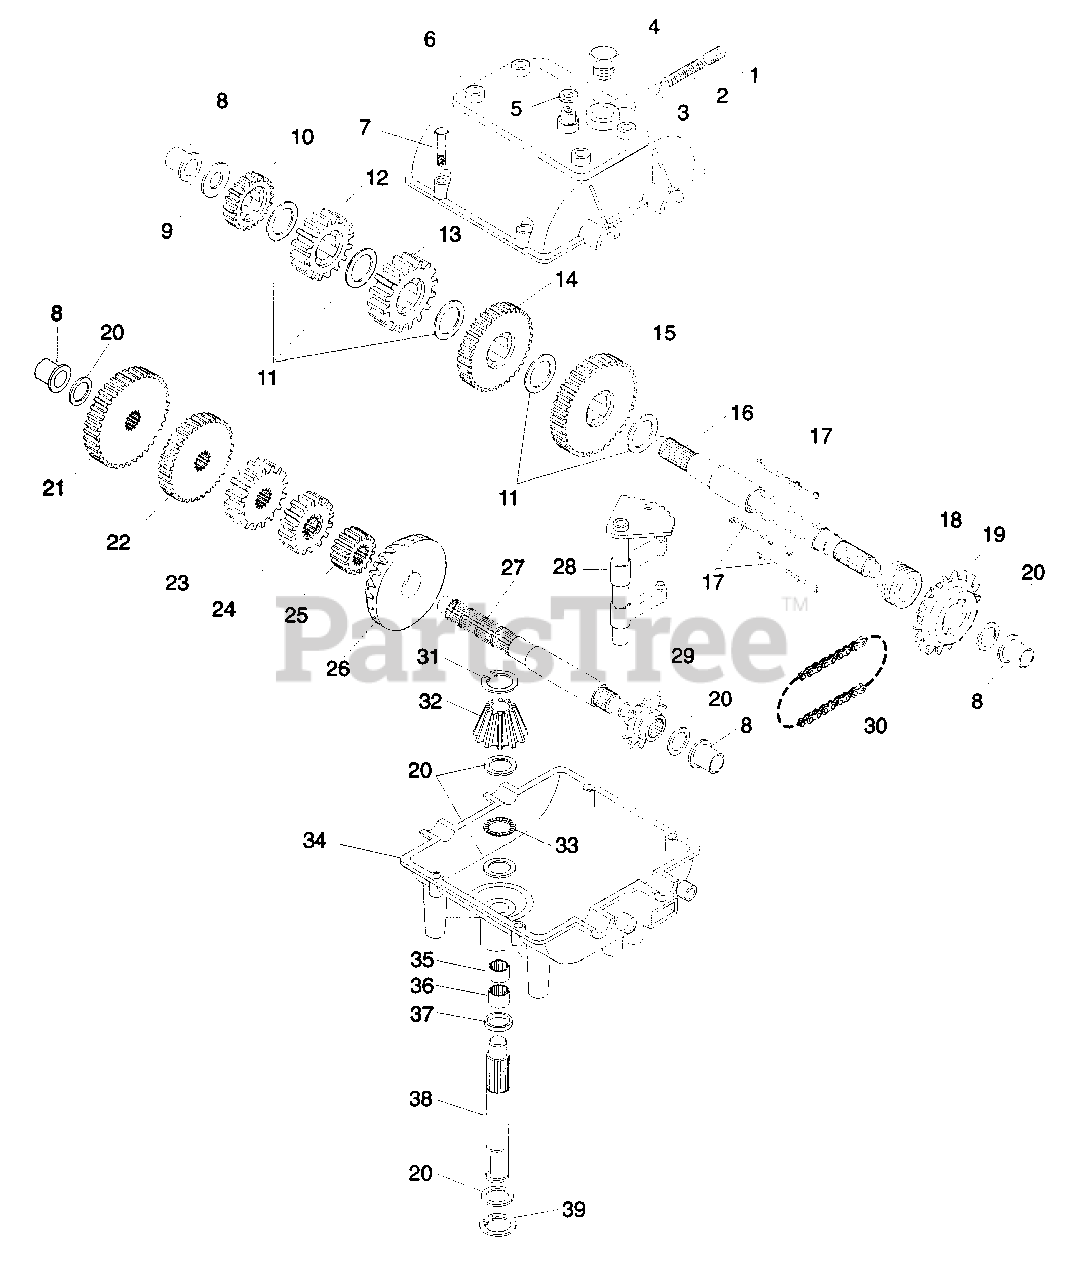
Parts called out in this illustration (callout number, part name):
1	Screw, Set 3/8-16 x 3/8
3	Ball, Steel 5/16
4	Plug, Threaded
5	Seal, Square Cut
6	Cover, Transmission
7	Screw, HHD Taptite, 1/4-20 x 1.25
8	Bushing, Flanged
9	Washer, Thrust
10	Gear, Spur (27 Teeth)
11	Washer, Thrust
12	Gear, Spur (30 Teeth)
13	Gear, Spur (32 Teeth)
14	Gear, Spur (35 Teeth)
15	Gear, Spur (37 Teeth)
16	Shaft, Output & Brake
18	Collar, Shift
19	Sprocket (18 Teeth)
20	Washer, Thrust
21	Gear, Spur (23 Teeth)
22	Gear, Spur (20 Teeth)
23	Gear, Spur (18 Teeth)
24	Gear, Spur (15 Teeth)
25	Gear, Spur (12 Teeth)
26	Gear, Bevel (42 Teeth)
27	Shaft, Counter
28	Rod & Fork Assembly, Shift
29	Sprocket (9 Teeth)
30	Chain, Roller
31	Ring, Retaining
32	Bevel Pinion, input
33	Bearing, Thrust
34	Case, Transmission
35	Bearing, Needle
36	Bearing, Needle
38	Shaft, Input
39	Ring, Retaining
